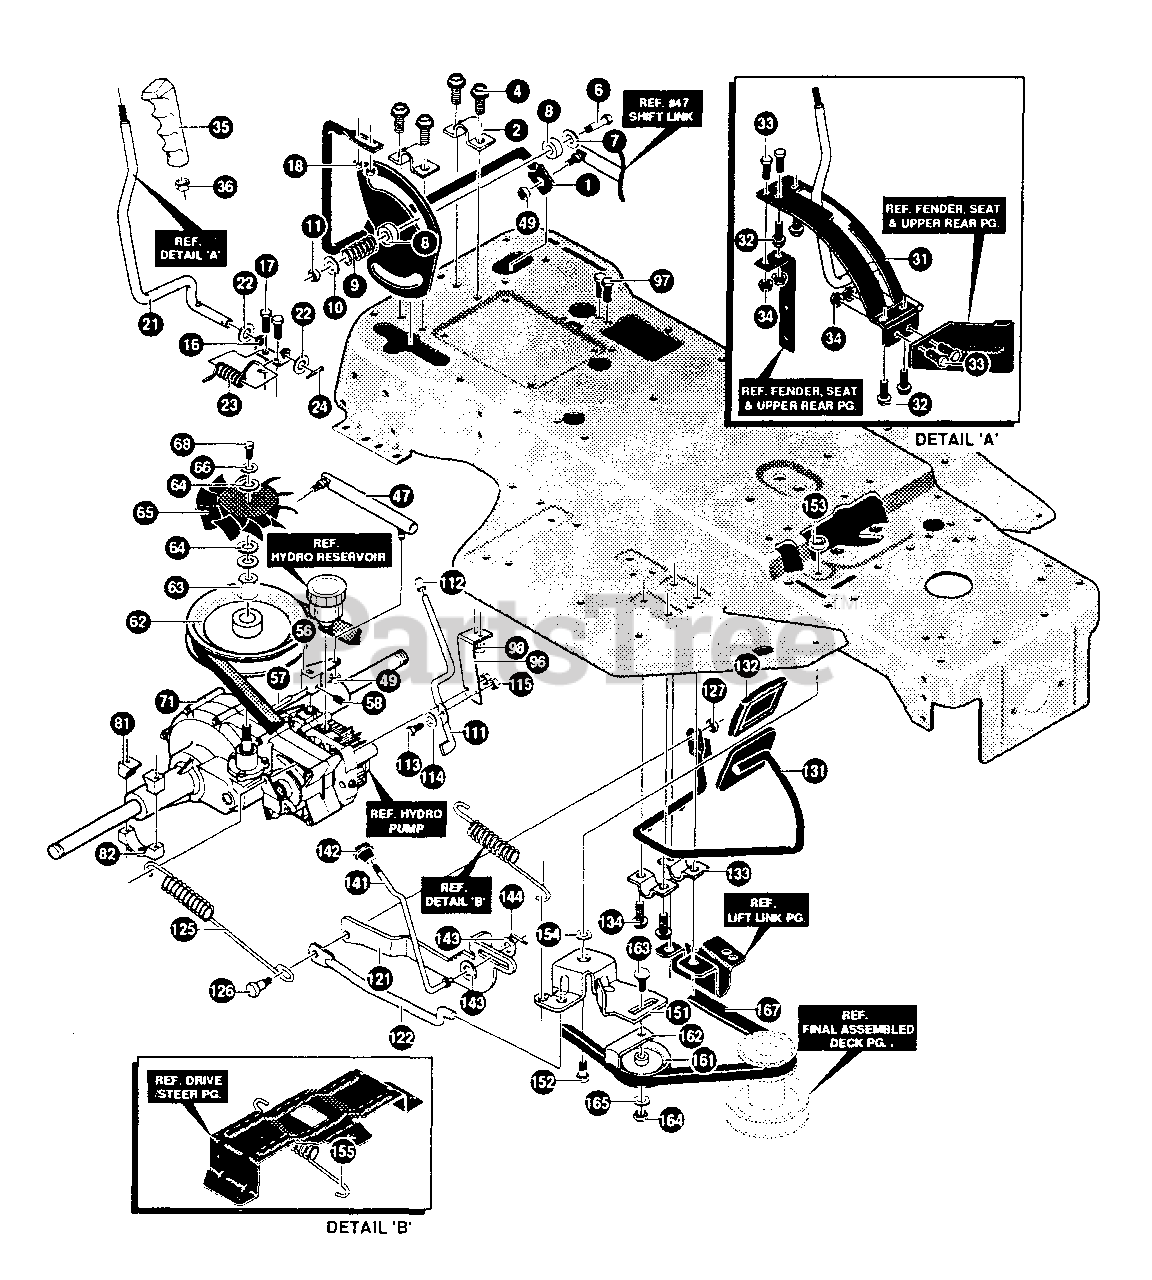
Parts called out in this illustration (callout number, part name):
1	SHIFT ROD, ASSY
2	BRACKET CL/BR ARM
4	SCREW, 5/16-18X.50 WAHHTAP
6	SCREW, 5/16-18X2.00 HHC
7	WASHER, FLAT .390X1.25X .119
8	WASHER, FRICTION 1.25ODX.34ID
10	WASHER, FLAT .344X.69X.065
11	NUT 5/16-18 REGHEXCTRLK
16	BRACKET, PIVOT SHIFT LEVER
17	SCREW, 1/4-20X.75 HHC
18	NUT, 1/4-20 WDFL MAC-LOCK
21	ROD SHIFT
22	WASHER, FLAT .469X.92X.065Y
23	SPRING-TORSION HYDRO SHIFT
24	PIN, COTTER .090 DIAX.75LG
31	QUADRANT SHIFT HYDRO
32	SCREW, #10 X .50 HHTAPPST
33	SCREW, 1/4-20X.75 HHC
34	NUT 1/4-20 WDFLWHIZ-LK
35	HANDLE 1/2-13 MOLDED
36	NUT 1/2-13 HEXJAM
47	SHIFT LINK ASS'Y .625DIA
49	NUT 3/8-24 HXCTRLK
56	ARM SPEED CONTROL HYDRO
57	PIN SPRING .187DIAX.88LG HVPL
58	SCREW 1/4-20X.38NYLALHSETCPPT
62	PULLEY ASSY HYDRO
63	NUT PULLEY 1/2-20 AND 1/4-20
64	WASHER, FLAT .281X1.25X.06
65	FAN HYDRO 7.00DIA-10 BLADES
66	WASHER, REGSPTLK .263X.49X.07
68	SCREW, 1/4-20X.75 HHC
71	TRANSAXLE, HG #217-1010S
81	MOUNTING BLOCK LH HYDRO
82	MOUNTING BLOCKS HYDRO
96	STABILIZER BRACKET
97	SCREW 5/16-18X.75 HHC
98	NUT 5/16-18 REGHEXCTRLK
111	ROD-RELIEF VALVE
112	CAP MEMORY ROD .38ID X .75
113	BOLT .250X.312 HHSH 1/4-20
114	WASHER .39IDX1.25DX.07 BELLVIL
115	NUT 5/16-18 REGHEXCTRLK
121	LEVER PARK BRAKE
122	ROD CLUTCH
125	SPRING BRAKE HG HYDRO (EURO)
126	BOLT .500X.500 HHSH 5/16-18
127	NUT 5/16-18 REGHEXCTRLK
131	ASSY WELD CL/BR ROD
132	PAD CLUTCH/BRAKE MOLD W/L
133	BRACKET CL/BR ARM
134	SCREW, 5/16-18X.50 WAHHTAP
141	ROD PARKING BRAKE
142	KNOB PARK BRAKE
143	WASHER, FLAT .250X.56X.049
144	PIN COTTER .062 DIAX .75LG
151	ARM IDLER
152	BOLT .621X.143 HHSH 5/16-18
153	NUT 5/16-18 REGHEXCTRLK
154	WASHER, FLAT .333X.87X.119
155	SPRING,CLUTCH .113X.750X6.88
161	PULLEY, IDLER V4L 3.12EFF DIA
162	RETAINER, BELT
163	BOLT, 3/8-16X1.50 CARR
164	NUT 3/8-16 REGHX
165	WASHER, REGSPTLK .393X.68X.10
167	BELT V 4L 82.5 HYDRO TRACTION
